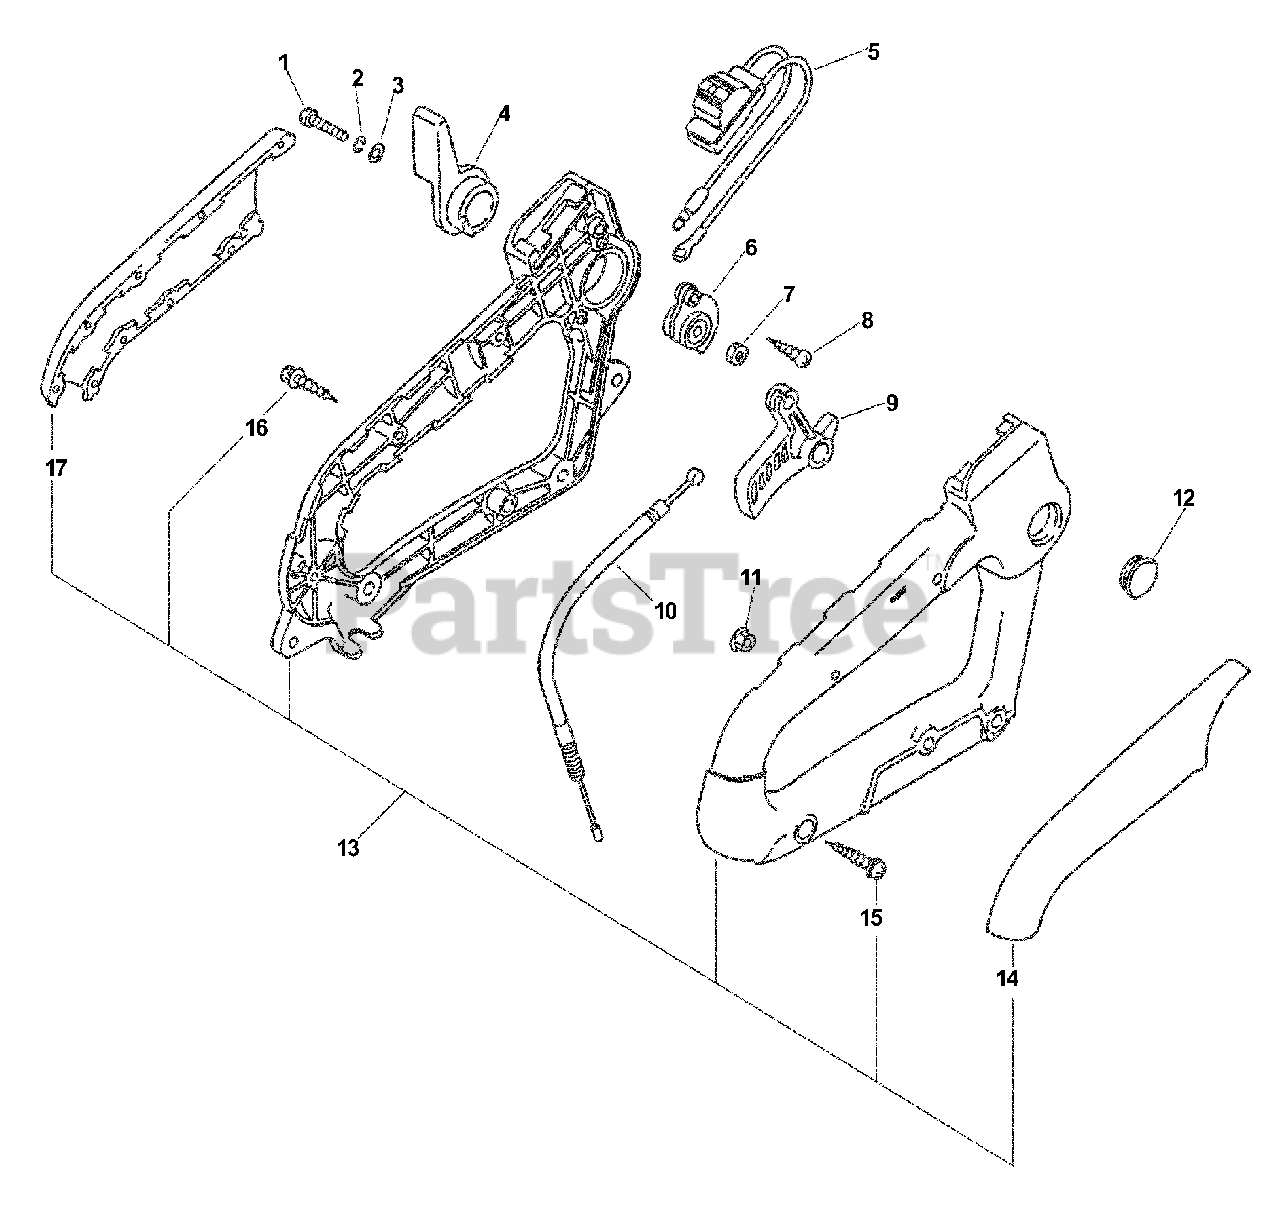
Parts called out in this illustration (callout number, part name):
1	SCREW 6×20
2	WASHER, SPRING 6
3	WASHER 6.5×13×1
4	CONTROL, THROTTLE
5	SWITCH, ON-OFF
6	BRACKET, THROTTLE
7	NUT, HEX M6
8	SCREW 4×10
9	TRIGGER, THROTTLE
10	CABLE, THROTTLE
11	NUT, FLANGE M5
13	HANDLE KIT
14	GRIP, RIGHT
15	SCREW 5×30
16	SCREW 4×22
17	GRIP, LEFT
